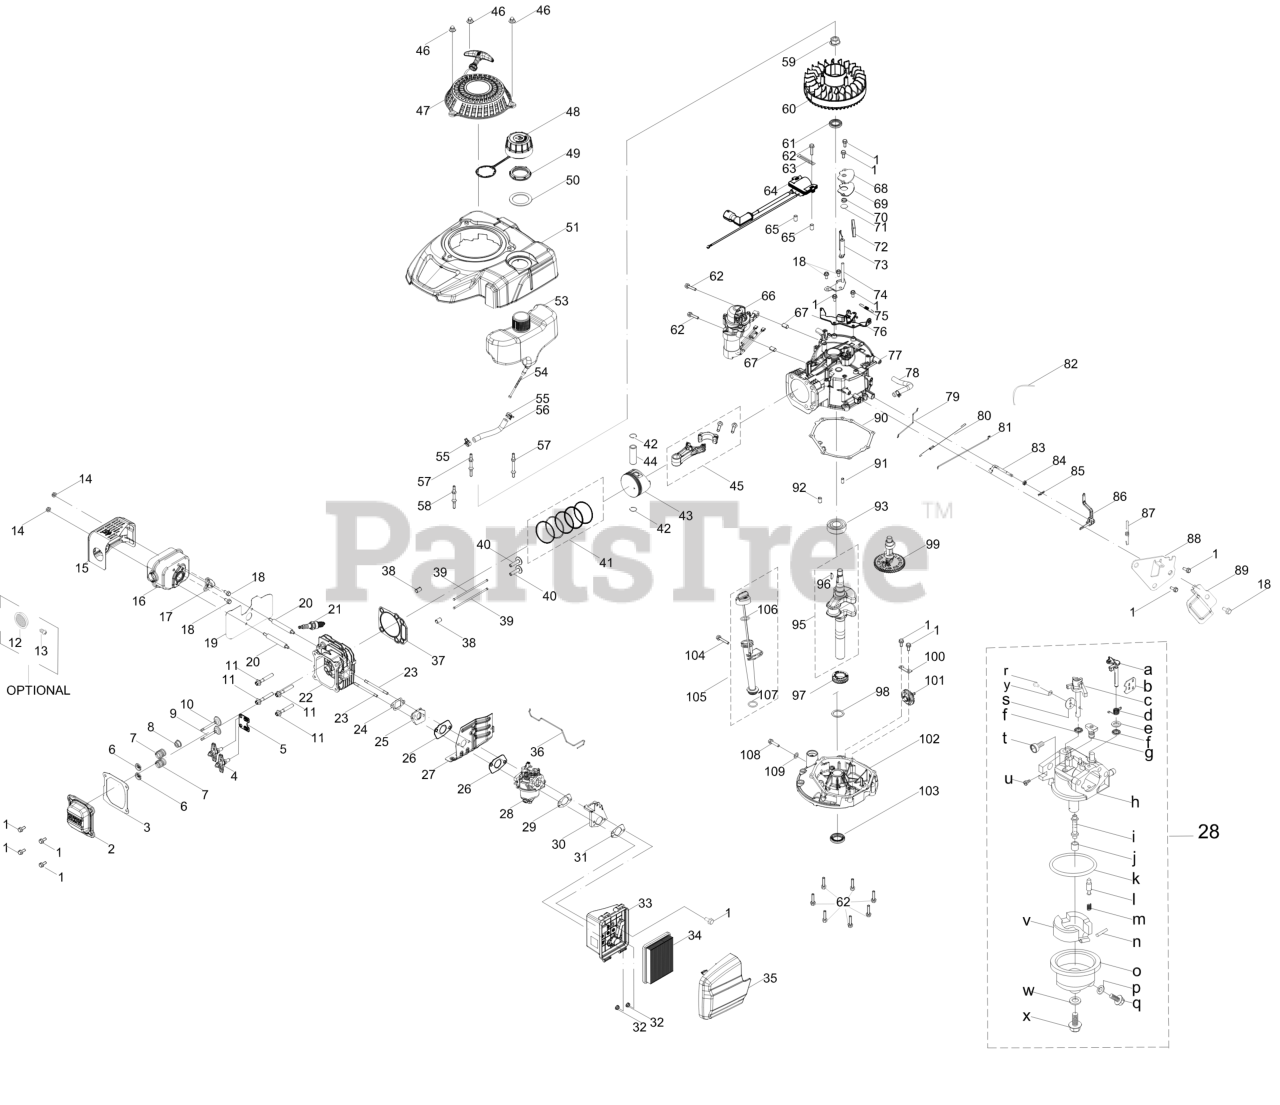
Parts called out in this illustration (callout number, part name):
1	BOLT M6-1 x 14 GR8.8
2	VALVE COVER
3	VALVE COVER GASKET
4	ROCKER ARM ASSEMBLY
5	PUSH ROD GUIDE
6	INTAKE VALVE SPRING RETAINER
7	VALVE SPRING
8	INTAKE VALVE SEAL
9	EXHAUST VALVE
10	INTAKE VALVE
11	SCREW M8 x 54 GR10
12	SPARK ARRESTOR
13	SCREW M3.5 x 9.5
14	HEX NUT
15	MUFFLER SHIELD
16	MUFFLER ASSEMBLY
17	THERMOSTAT
18	BOLT M6-1 x 12 GR8.8
19	MUFFLER GASKET
20	STUD M6-1 x 95
21	SPARK PLUG
22	CYLINDER HEAD
23	STUD M6 x 90
24	CARBURETOR GASKET
25	CARBURETOR INSULATOR
26	CARBURETOR GASKET
27	HEAT SHIELD
28	CARBURETOR ASSEMBLY HY-5X70A
29	AIR FILTER BRACKET GASKET
30	AIR FILTER BRACKET
31	AIR FILTER BASE GASKET
32	HEX NUT
33	AIR FILTER HOUSING BASE
34	AIR FILTER
34	Cub Cadet AIR FILTER
34	Genuine Factory Parts AIR FILTER
35	AIR FILTER COVER
36	TEMPERATURE CONTROL LINKAGE
37	CYLINDER HEAD GASKET
38	DOWEL PIN
39	PUSH ROD
40	TAPPET
41	PISTON RING 4PC SET
42	PISTON PIN SNAP RING
43	PISTON ASSEMBLY
44	PISTON PIN
45	CONNECTING ROD ASSEMBLY
46	ACORN NUT
47	RECOIL STARTER ASSEMBLY
48	FUEL CAP W/TETHER
49	FUEL TANK NUT
50	FUEL TANK UPPER GROMMET
51	ENGINE SHROUD W/O IGNITION SWITCH
53	FUEL TANK
54	FUEL FILTER
54	Genuine Factory Parts FUEL FILTER
55	HOSE CLAMP
56	FUEL HOSE
57	STARTER/SHROUD REAR STUD
58	STARTER SHROUD FRONT STUD M6X74
59	FLYWHEEL NUT
60	FLYWHEEL ASSEMBLY
61	CRANKSHAFT SEAL
62	BOLT-M6-1 x 28 GR8.8
63	FLEXIBLE CLAMP
64	IGNITION COIL ASSEMBLY
65	IGNITION COIL SPACER
66	ELECTRIC STARTER ASSEMBLY
67	DOWEL PIN
68	BREATHER COVER PLATE
69	BREATHER GASKET
70	BREATHER VALVE SPRING
71	BREATHER VALVE
72	BREATHER SCREEN
73	AIR VANE
74	AIR VANE BRACKET
75	ENGINE BRAKE SPRING
76	ENGINE BRAKE ASSEMBLY
77	CRANKCASE
78	BREATHER HOSE ASSEMBLY
79	CHOKE LINKAGE
80	THROTTLE SPRING
81	THROTTLE LINKAGE
82	CABLE TIE - 3 x 150
83	GOVERNOR ARM SHAFT
84	GOVERNOR SEAL
85	COTTER PIN
86	GOVERNOR ARM ASSEMBLY
87	GOVERNOR SPRING
88	COMPONENT BRACKET
89	GOVERNOR SHIELD
90	CRANKCASE COVER GASKET
91	DOWEL PIN
92	DOWEL PIN
93	BEARING
95	CRANKSHAFT
96	FLYWHEEL KEY
97	DRIVE TIMING GEAR
98	THRUST WASHER
99	CAMSHAFT
100	GOVERNOR GEAR MOUNTING PLATE
101	GOVERNOR GEAR/SHAFT ASSEMBLY
102	CRANKCASE COVER
103	LOWER CRANKSHAFT OIL SEAL
104	BOLT M6-1 x 35 GR8.8
105	OIL DIPSTICK ASSEMBLY
106	O-RING
107	O-RING
108	OIL DRAIN PLUG
109	WASHER
